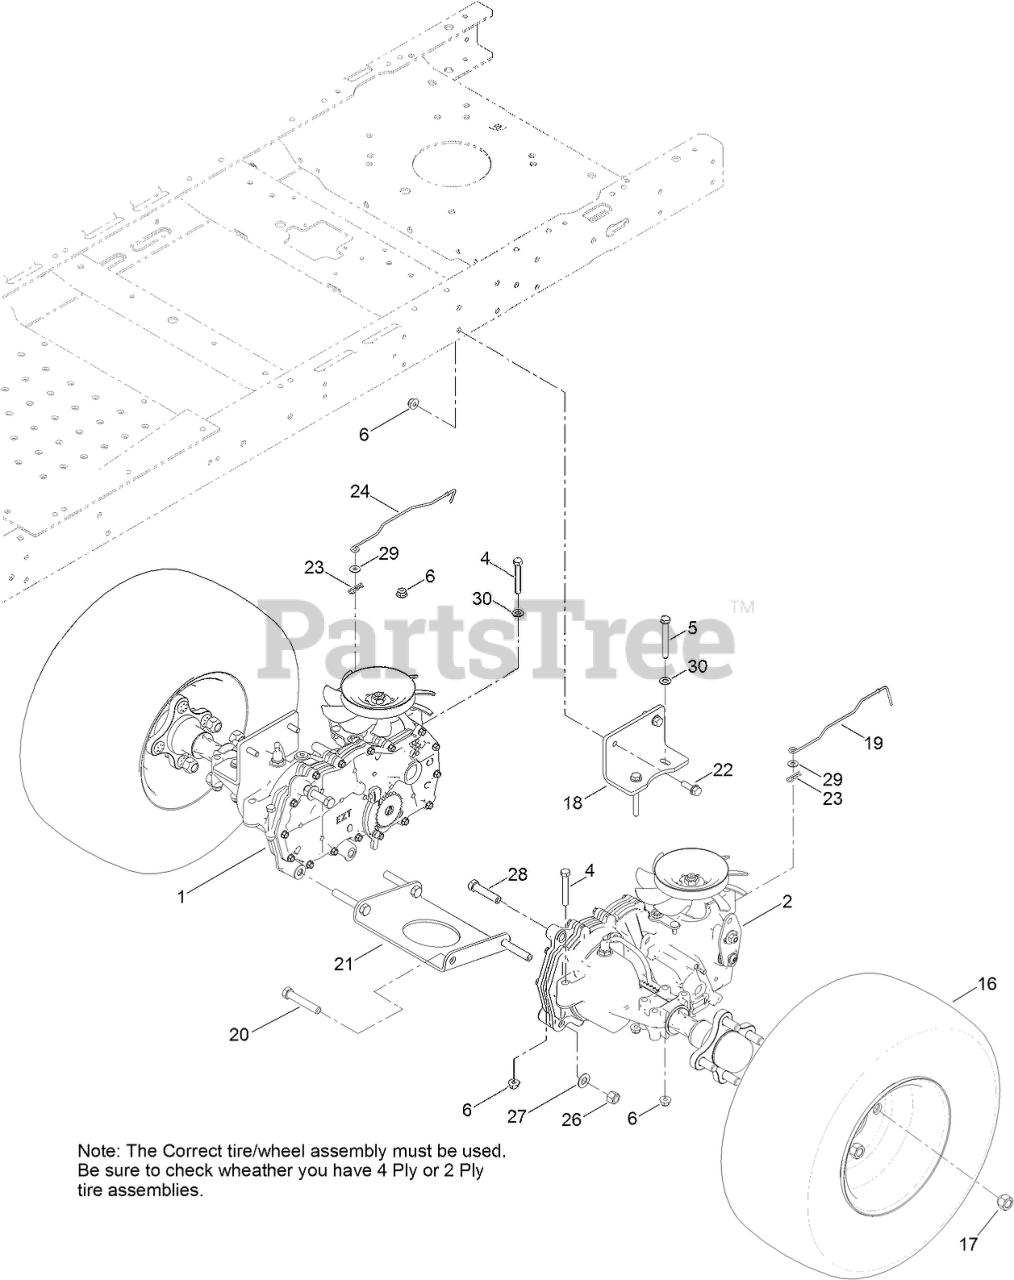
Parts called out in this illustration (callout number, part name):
1	RH HYDRO TRANSMISSION ASM
2	LH HYDRO TRANSMISSION ASM
4	SCREW-HH
5	SCREW-HH
6	NUT-HF, NI
16	4 PLY WHEEL AND TIRE ASM
16	2 PLY TIRE AND WHEEL ASM
17	NUT-LUG
18	MOUNT-HYDRO
19	ROD-BYPASS, LH
20	SCREW-HH
21	PLATE-CROSS, HYDRO
22	SCREW-HHF
23	PIN-COTTER
24	ROD-BYPASS, RH
26	NUT-LOCK, NI
27	WASHER-FLAT
28	SCREW-HH
29	WASHER
30	WASHER-PLAIN
